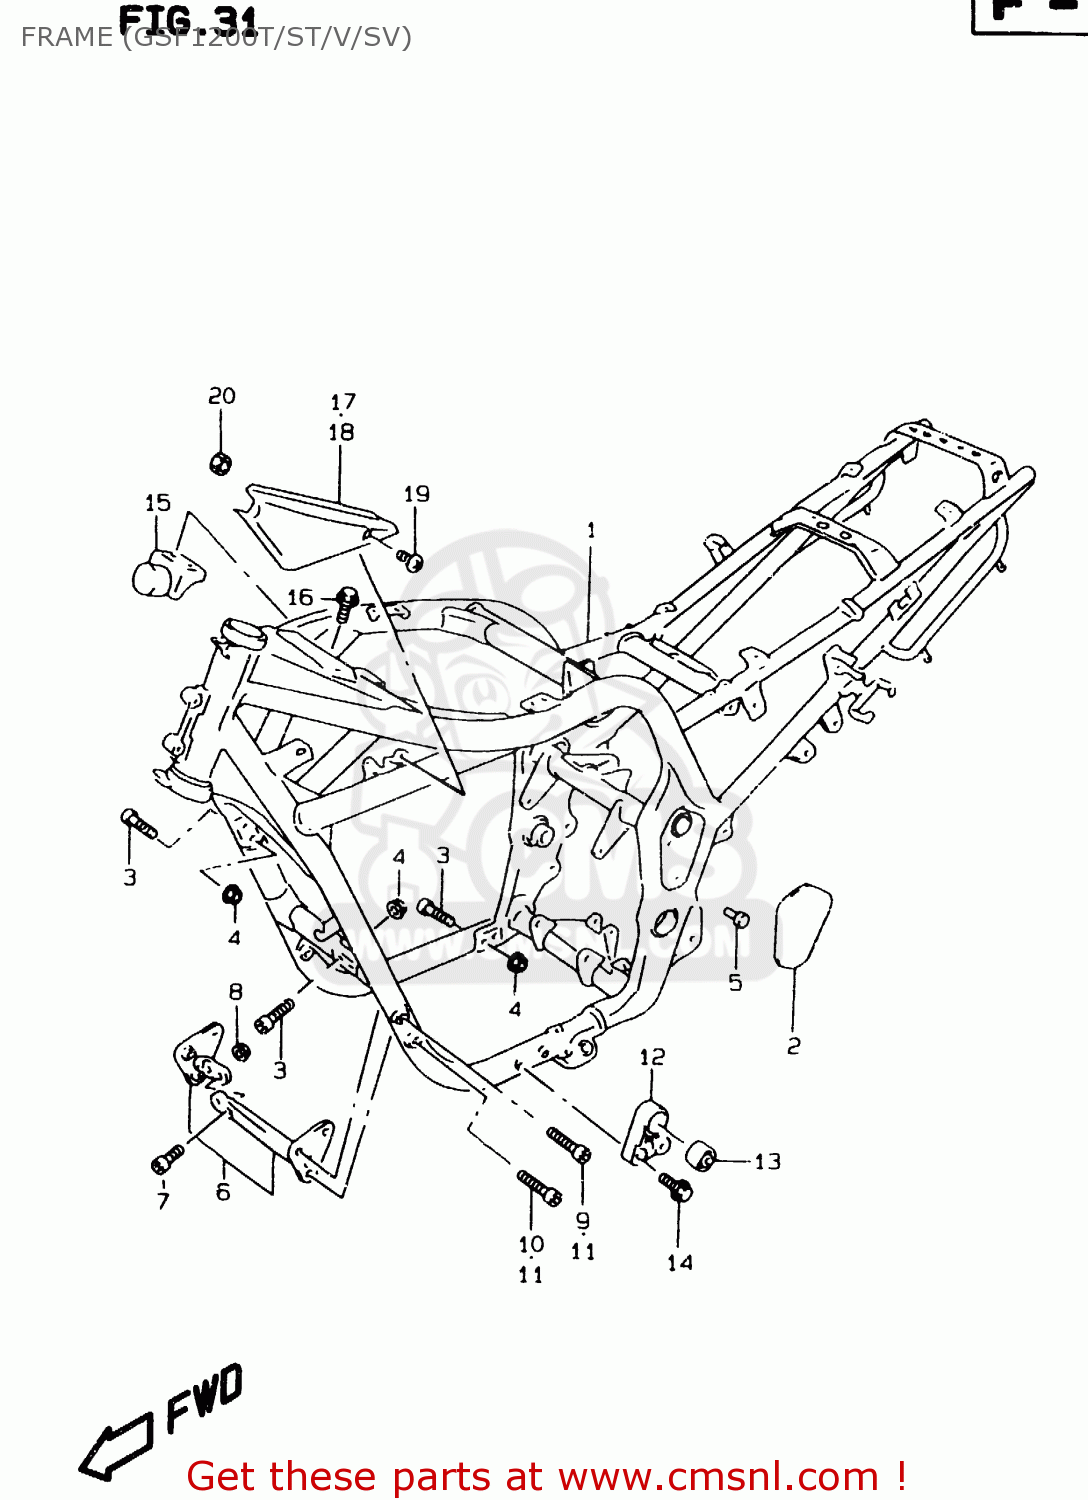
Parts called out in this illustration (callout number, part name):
1	FRAME COMP
2	COVER,FRAME BODY,R
3	BOLT(10X33)
4	NUT
5	CLIP
6	PLATE,ENGINE MOUNT NO.1
7	BOLT
8	NUT
9	BOLT
10	BOLT
11	BOLT
12	BRACKET,ENGINE MOUNTING NO.2
13	BUSH,ENG MOUNTING NO.2
14	BOLT
15	DAMPER COMP,FRAME
16	BOLT
17	COVER,FRAME HEAD,R
18	COVER,FRAME HEAD,L
19	SCREW(5X12)
20	CUSHION
